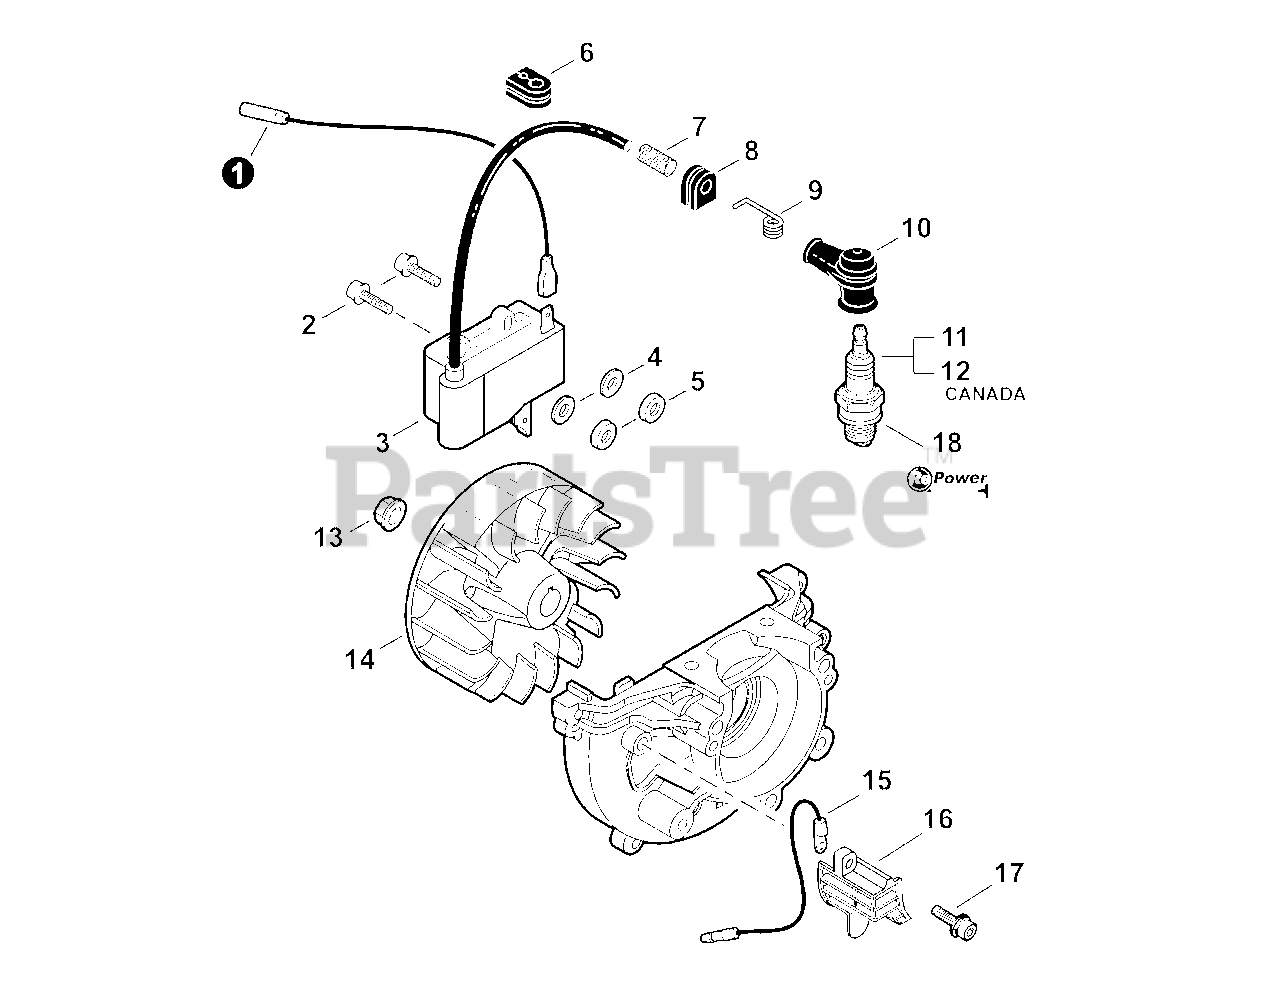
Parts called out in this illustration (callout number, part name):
1	LEAD - IGNITION
3	COIL, IGNITION
4	WASHER 4 MM
5	INSULATOR 4
6	GROMMET
7	TUBE, INSULATOR
9	TERMINAL, SPARK PLUG
10	CAP, SPARK PLUG
11	SPARK PLUG - BPM8Y
12	SPARK PLUG - BPMR8Y
13	NUT, FLANGE M8
14	FLYWHEEL
15	LEAD - GROUND
16	COVER, DUST
17	BOLT 5×16
18	TUNE-UP KIT - REPOWER
